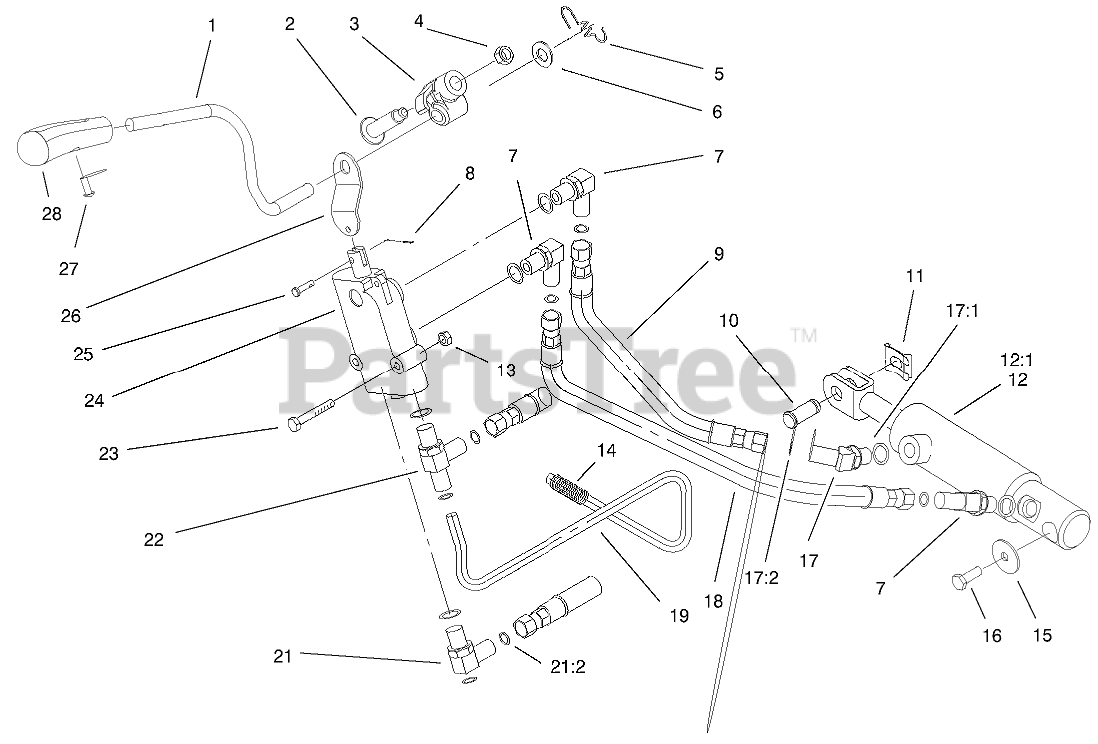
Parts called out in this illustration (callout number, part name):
1	HANDLE-LIFT
2	BOLT-SHOULDER
3	TRUNNION-LEVER, LIFT
4	NUT-JAM, LOCKING
5	SPRING-EXTENSION, LIFT
6	WASHER
7	FITTING-HYD, 90 DEGREE
8	PIN-COTTER
9	HOSE ASM
10	PIN-CLEVIS
11	CLIP-PIN
12	LIFT CYLINDER ASM
13	NUT-LOCK, NI
14	COVER-BRACE
15	WASHER-FLAT
16	SCREW-THREAD LOCKING
17	FITTING-HYD, 45 DEGREE
17:1	O-RING
17:2	O-RING
18	HOSE ASM
19	TUBE-HYD
21	FITTING-HYD, 90 DEGREE
22	FITTING-HYD, TEE
23	SCREW-HH
24	VALVE-HYD
25	PIN-CLEVIS
26	LINK-LIFT
27	SCREW-PPHTF
28	Knob-Lift (only on: 73552)
28	Knob-Lift (Int-l)(only on: 73590)
